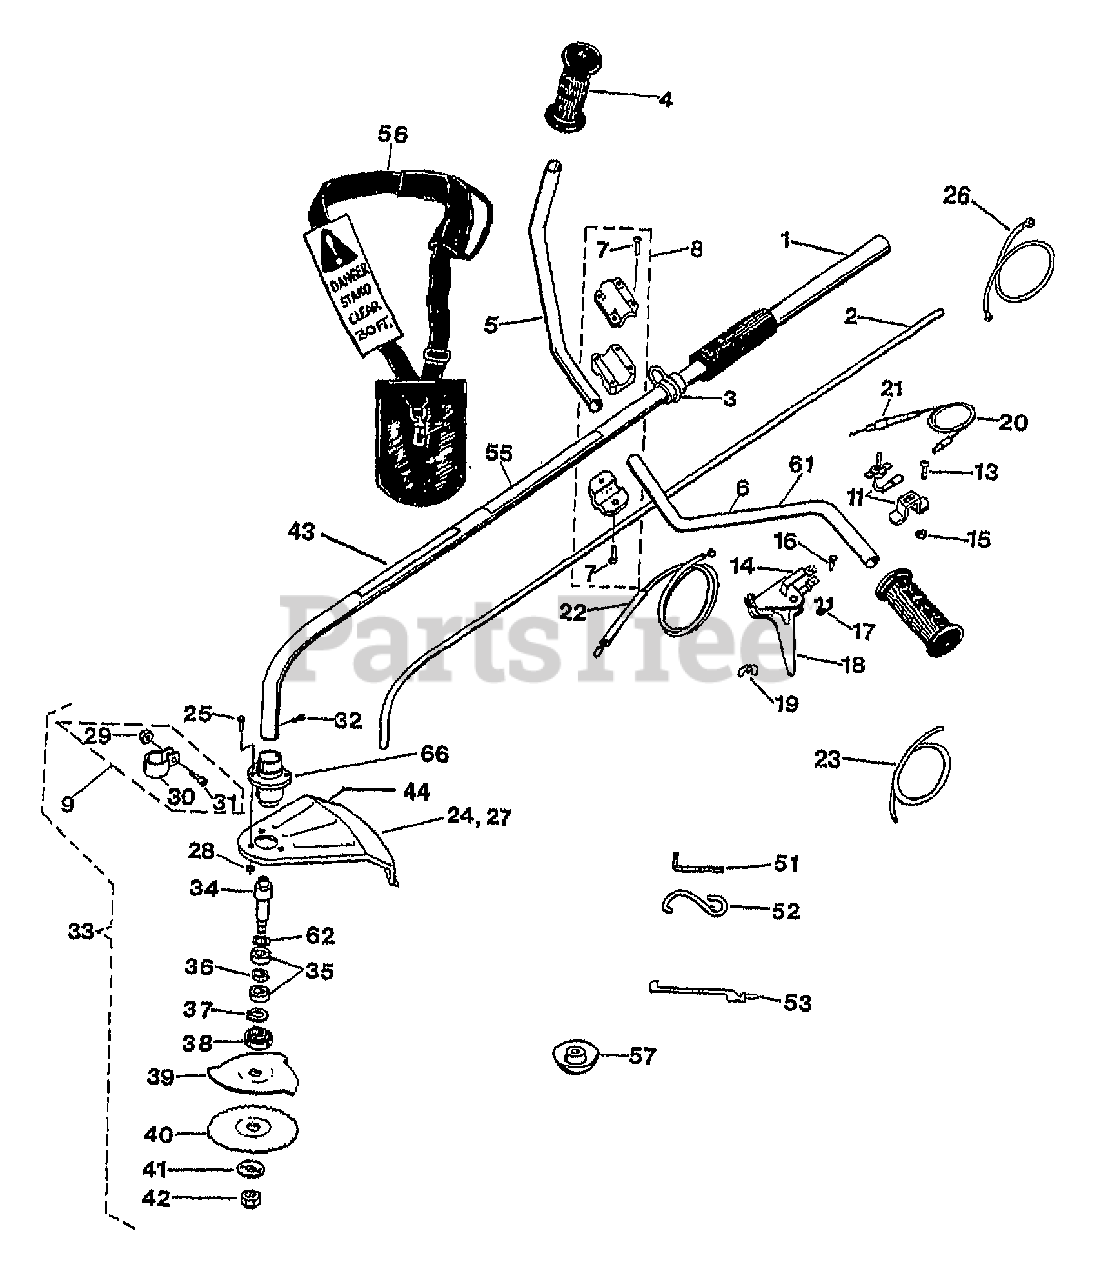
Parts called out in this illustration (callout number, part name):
1	HOUSING-DRIVESHAFT
2	SHAFT-DRIVE 5/16X57"
3	RING-CARRYING
4	GRIP-HANDLEBAR
5	HANDLEBAR-RH W/GRIP
6	HANDLEBAR-LH W/GRIP
7	SCR-HXSKT 1/4-20X.75 (ONLY AVAILABLE IN ITEM NO. 8)
8	KIT-H/BAR CLAMP (INCL. 7)
9	KIT (INCL. 29-31)
11	SWITCH-ON/OFF (INCL. BRACKET)
13	SCR-PHP M10-32X.75 ZP
14	KIT-CLAMP TRG. H205596
15	NUT-HH M10-32X.125
16	SCREW, HEX HD #10-32X1"
17	SPRING, THROTTLE CONTROL
18	ASSM-TRIGG H205532 (INCL. 16-19)
19	NUT, WING #10-32
21	WIRE CONNECTOR & COVER
22	CABLE-THROTTLE
23	COVER-CABLE
24	SHIELD-GRASS (INCL. 25,27,28)
25	SCR.& NUT
26	WIRE-GROUND
27	SHIELD-GRASS
28	KIT-HDW DUSTSHIELD
29	NUT-HF/LK 1/4-20 ZP
30	CLAMP, LOWER HEAD (ONLY AVAILABLE IN #9)
31	SCR-HXSKT 1/4-20X.75
32	SCR #10-32X5/16
33	ASSM-LOWER HEAD (INCL. 9,34-38,41,42,62 AND 66)
34	LOWER ARBOR-SQUARE
36	ASSM-LOWER HEAD SPACER
37	RING-RETAINING
38	WASHER-CUP
39	BLADE-8" TRIKUT HOFFCO
40	BLADE-8" BRUSHCUTTER
41	WASHER-ARBOR 3/8
42	NUT W/NYLON INSERT 3/8-24
43	DECAL-LOGO TROY-BILT
44	KIT-LINE CUT OFF (INCL. BLADE & BLADE MOUNTING HARDWARE)
51	WRENCH-ALLEN 3/16
52	LOWER HEAD TOOL
53	TIE-CABLE
55	DECAL-H/B LUBE INST
56	HARNESS W/HIP PAD RH
56	HARNESS-LEFT HAND
57	KIT-GLIDE BALL
61	DECAL-GUARDIAN TRIANGLE
66	AVAILABLE IN ITEM NO. 33
